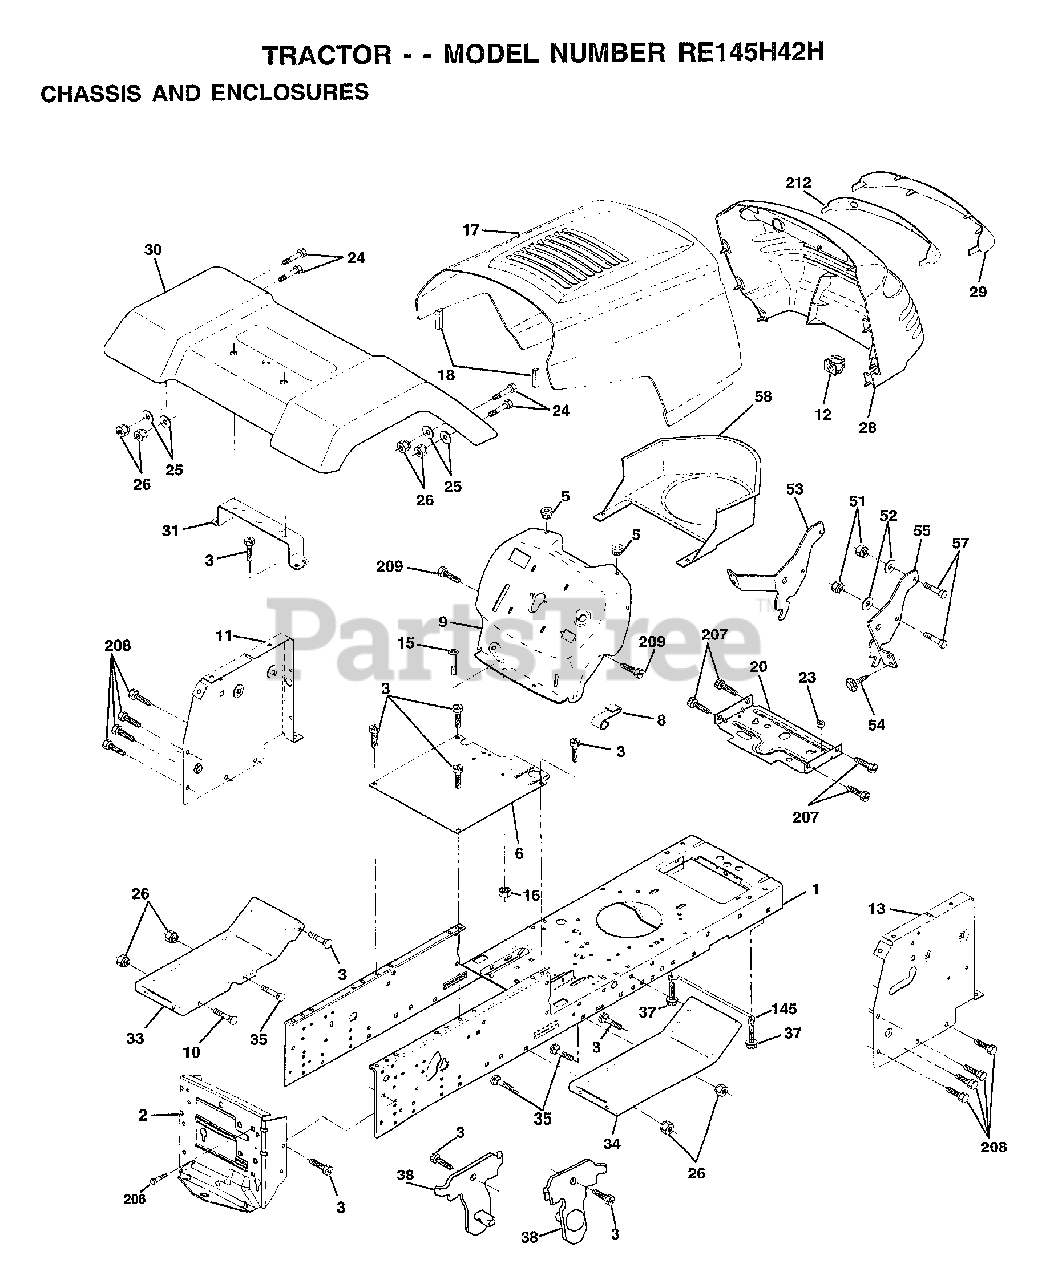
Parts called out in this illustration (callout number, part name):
2	DRAWBAR
3	SCREW
5	BUMPER-HOOD/DASH
6	SADDLE
8	CLIP.RETAINER
9	DASH
11	"PANEL-DASH,LH"
12	CLIP.TINNERMAN
15	SCREW
17	HOOD.STEEL.ASSY
20	"PLATE-MTG,BATT/FU"
24	BOLT
25	WASHER
26	NUT
28	GRILL.BLK
29	LENS.GRILLE.PRIVATE LABEL
31	BRKT FENDER
33	FOOTREST LH
34	FOOTREST RH
35	BOLT
37	SCREW LT
38	BRKT ASM PIVOT MOWER REAR
51	NUT
52	WASHER
53	BRACKET.GRILLE.LH
54	SCREW.HEX.WS.HD
55	BRACKET.GRILLE.RH
58	DUCT.AIR.B&S.18HP
145	"ROD POVOT,CHASSIS"
206	BOLT SHOULDER
207	SCREW
208	SCREW
209	SCREW
212	INSERT LENS REFLECT
